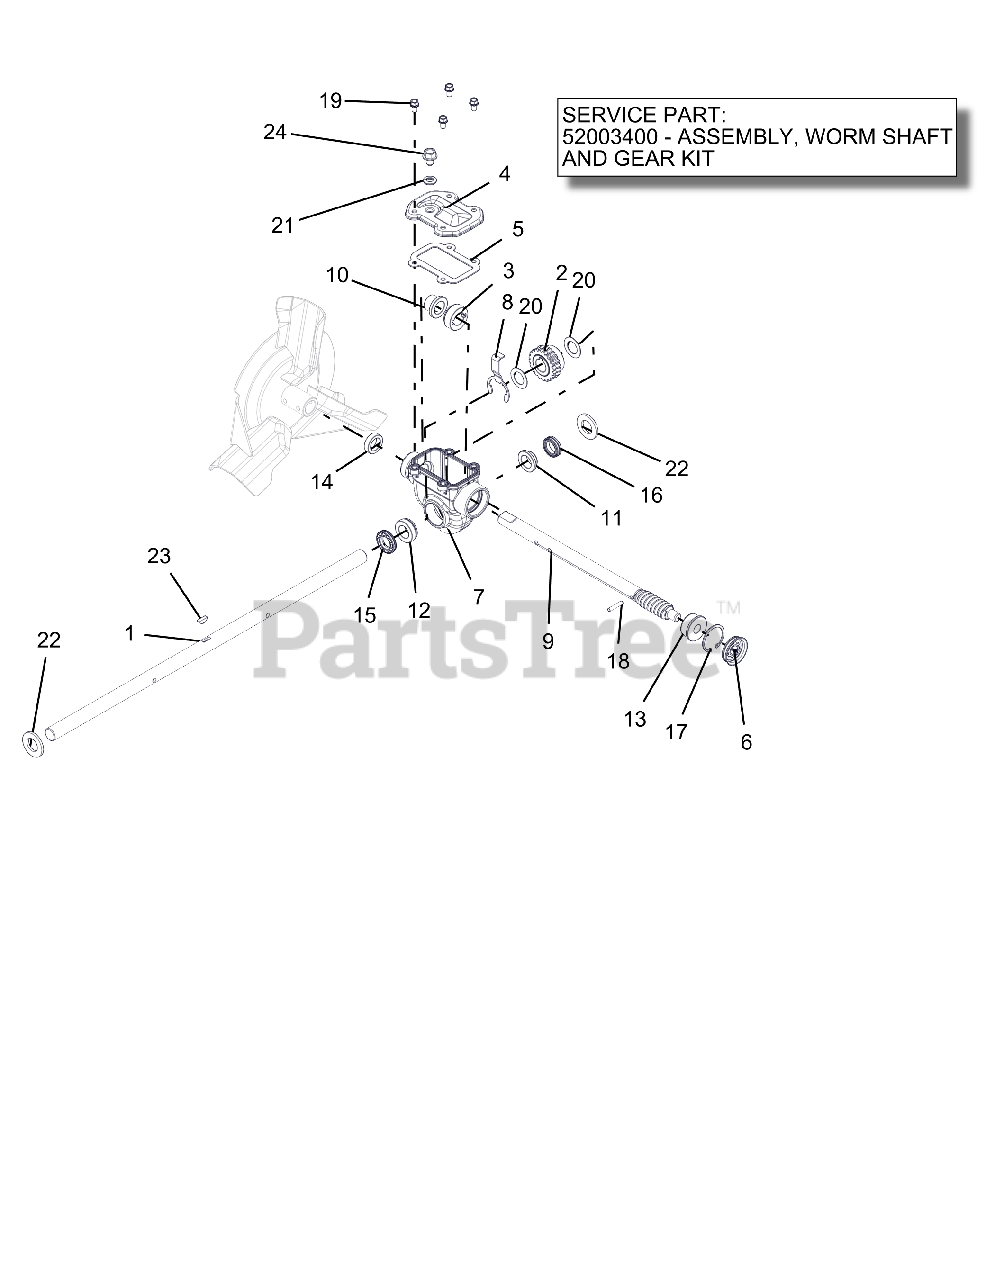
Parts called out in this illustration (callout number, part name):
1	SHAFT, RAKE - 24" (.750 DIA)
2	SHAFT AND WORM GEAR ASSEMBLY
3	THRUST COLLAR, .75" ID SLIPFIT
4	COVER, TOP - COMPACT
5	GASKET, TOP - COMPACT GEARCASE
6	COVER, GEAR CASE 1.50"
7	GEARCASE, COMPACT ALUMINUM
8	BUSHING RETAINER, COMPACT
9	SHAFT, WORM - COMPACT
10	BSHG-FLG .755X.878X.75X1.25
11	BSHG-FLG .755X.878X.424X1.25
12	BSHG-FLG COMPACT, RIGHT
13	BSHG-FLG .503X1.303X.62X1.465
14	SEAL-OIL .748X1.125X.312 TB2-H
15	SEAL-OIL .748X1.300X.250 TBC29
16	SEAL-OIL .748X1.125X.312 TBC29
17	RG-RTNG-INT 1.500X.050
18	PIN-STR .188X1.00 6150
19	BOLT, SEMS .25-20X.50 GR5 YWZC
20	WSHR-FL-STL .760X1.225X.032 YZ
21	WSHR-BND-SEAL .38X.75X.11 GALV
22	@WSHR-FL-STL.812X1.50X.135YWZC
23	KEY-WDRF .19X.63 HRD #61
24	@SCR-ROLOK .38-16X.50 HWH YWZC
25	WORM GEAR
